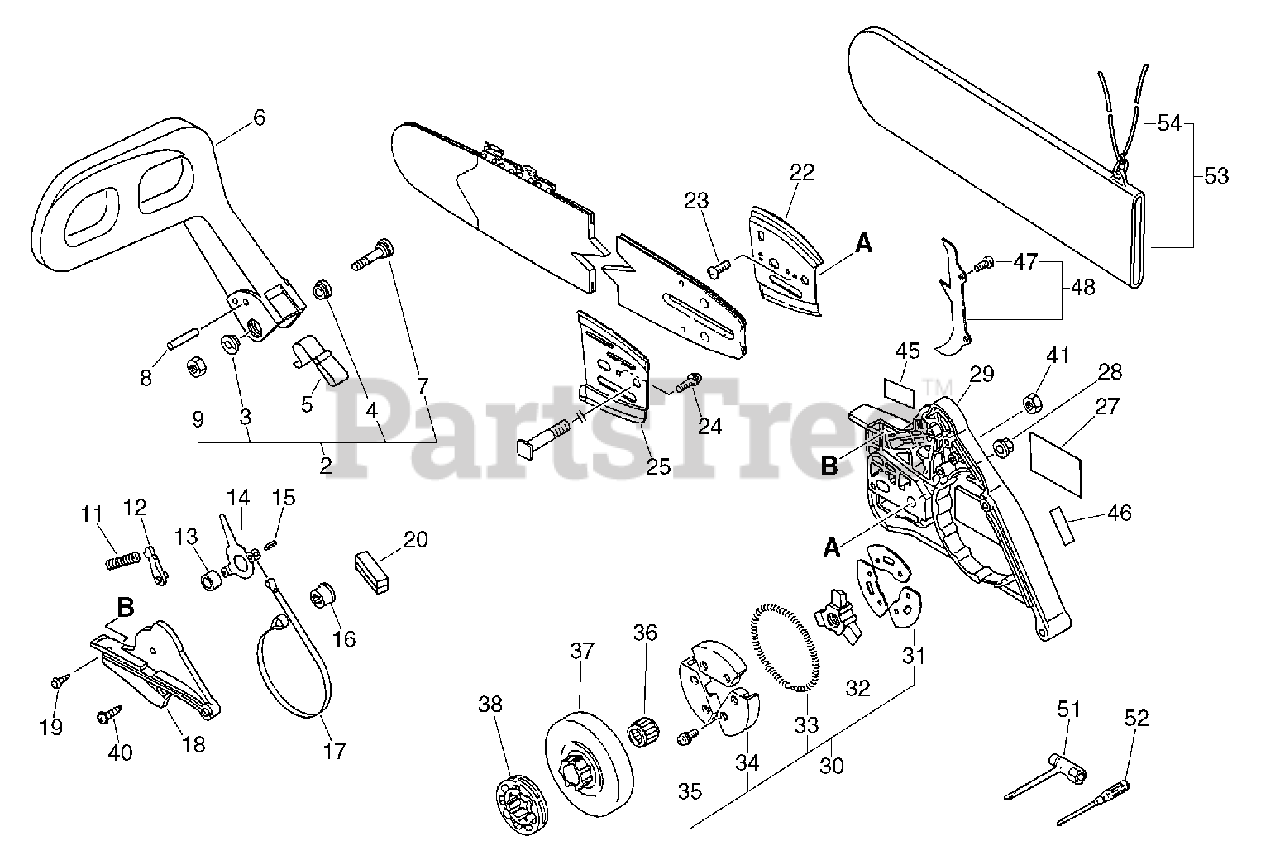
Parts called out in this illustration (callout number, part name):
2	MOUNTING KIT
4	COLLAR - 5
5	SPRING, RETURN
6	LEVER, BRAKE
7	SCREW - 5X35
8	PIN - 3.5X26
9	LOCKNUT - 5
11	SPRING, BRAKE
12	STOPPER, BRAKE
13	SPACER - 8
14	LEVER, BRAKE
15	PIN - SPRING -- 4X8
16	ADJUSTER, BRAKE BAND
17	BAND, BRAKE
18	COVER, BRAKE
19	SCREW - 4X12
22	PLATE, GUIDE - OUTER
23	SCREW - 3X6
24	SCREW - 4X8
25	PLATE, GUIDE - INNER
27	LABEL - ECHO
28	NUT - 8 -- FLANGE
29	GUARD, SPROCKET
30	CLUTCH ASSY
31	PLATE, CLUTCH
32	HUB, CLUTCH
33	SPRING, CLUTCH
34	CLUTCH SHOE SET
35	SCREW - 4X6
36	BEARING, NEEDLE
37	DRUM, CLUTCH
38	SPROCKET, RIM
40	SCREW - 3X18
45	LABEL - CAUTION
46	LABEL - CAUTION
48	SPIKE KIT
51	T-WRENCH
52	SCREWDRIVER
53	COVER, GUIDE BAR
